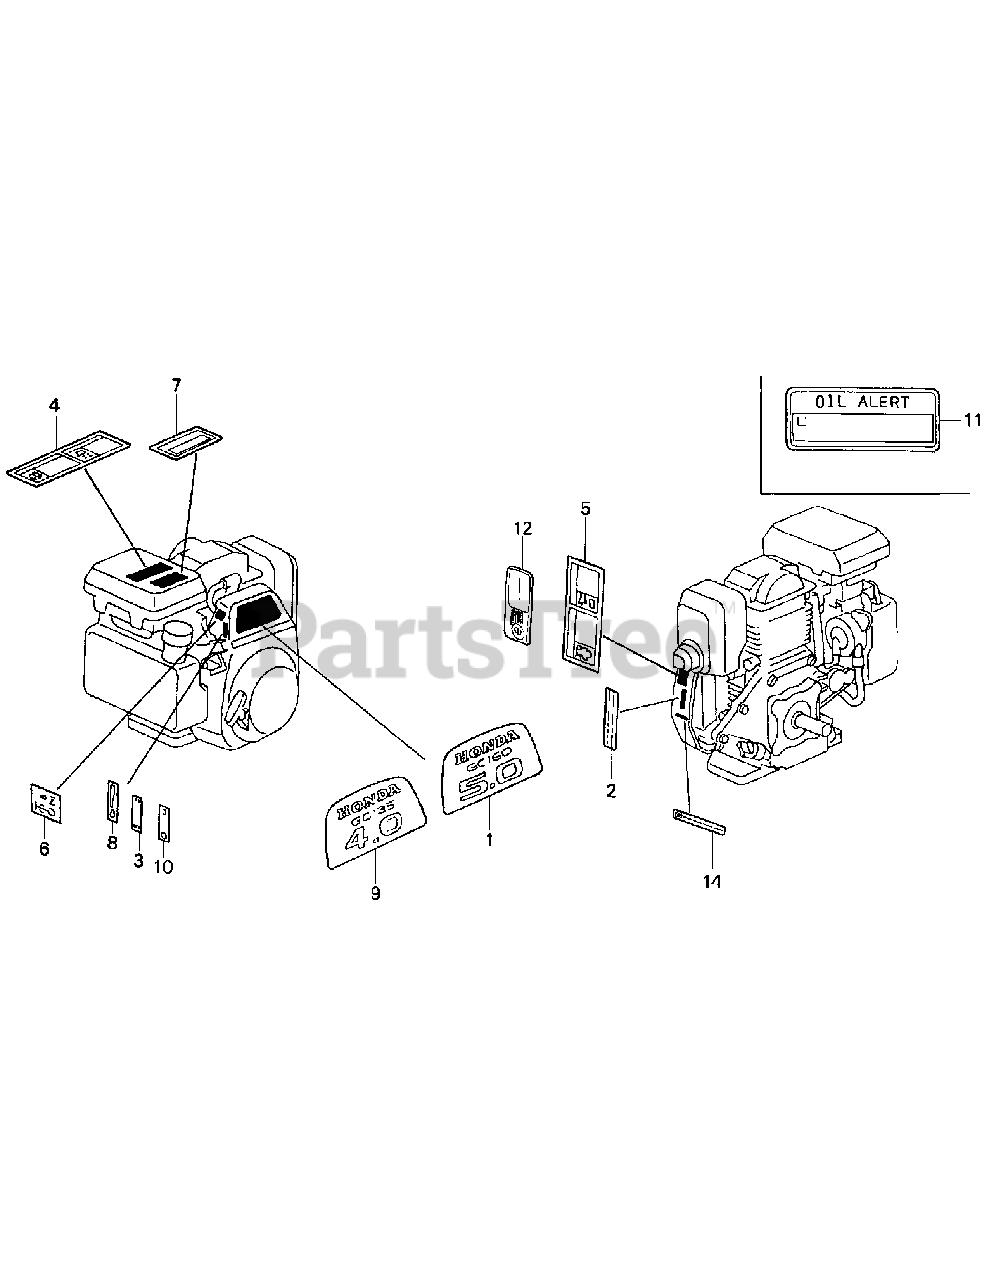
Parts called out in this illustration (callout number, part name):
1	MARK, EMBLEM (5.0)
1	EMBLEM (GC160 5.0)
6	MARK, CHOKE
8	MARK, THROTTLE INDICATION
